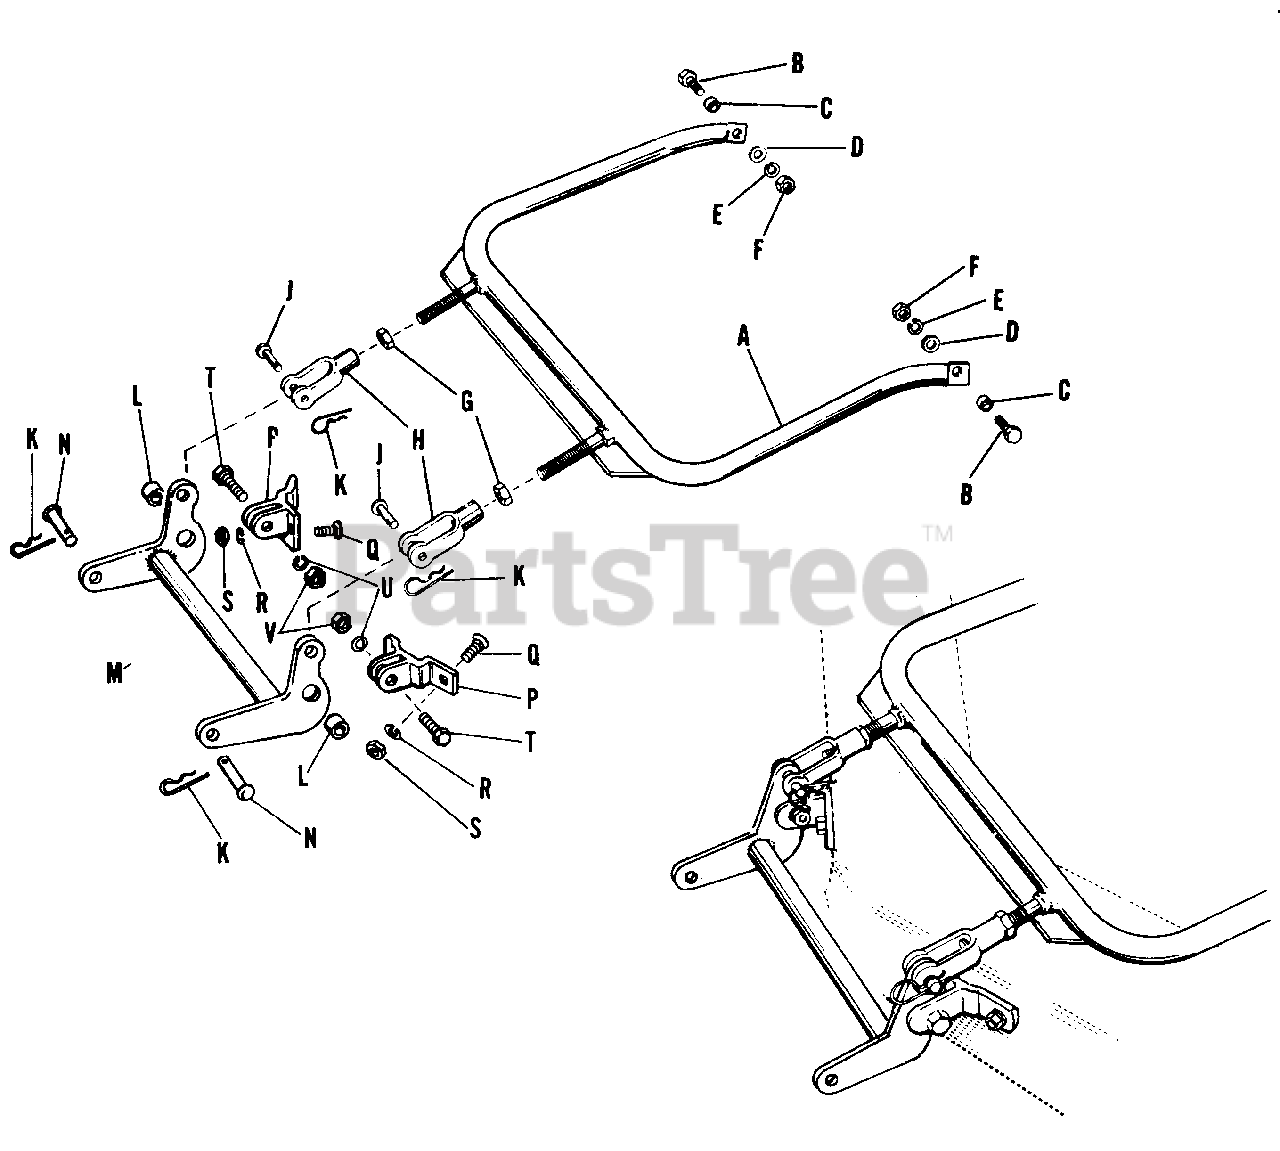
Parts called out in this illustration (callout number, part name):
A	Bail Assembly
B	Capscrew, Hex Hd., 1/2"-13 NC x 1 1/4" lg.
D	Washer, Plain, 7/16
E	Washer, Lock, 1/2"
F	Nut, Hex, Full, 1/2"-13 NC
G	Nut, Hex, Jam, 1/2"-20 NF
H	Yoke End, Adjusting
K	Clip, Spring
M	Rocker Arm
N	Pin
P	Bracket Assembly, Front
Q	Bolt, Carriage, 3/8"-16 NC x 1"
R	Washer, Lock, 3/8"
S	Nut, Hex, Full, 3/8"-16 NC
T	Capscrew, Hex, 1/2"-13 NC x 1 1/4"
U	Washer, Lock, 1/2"V
V	Nut, Hex., Full, 1/2"-13 NC
